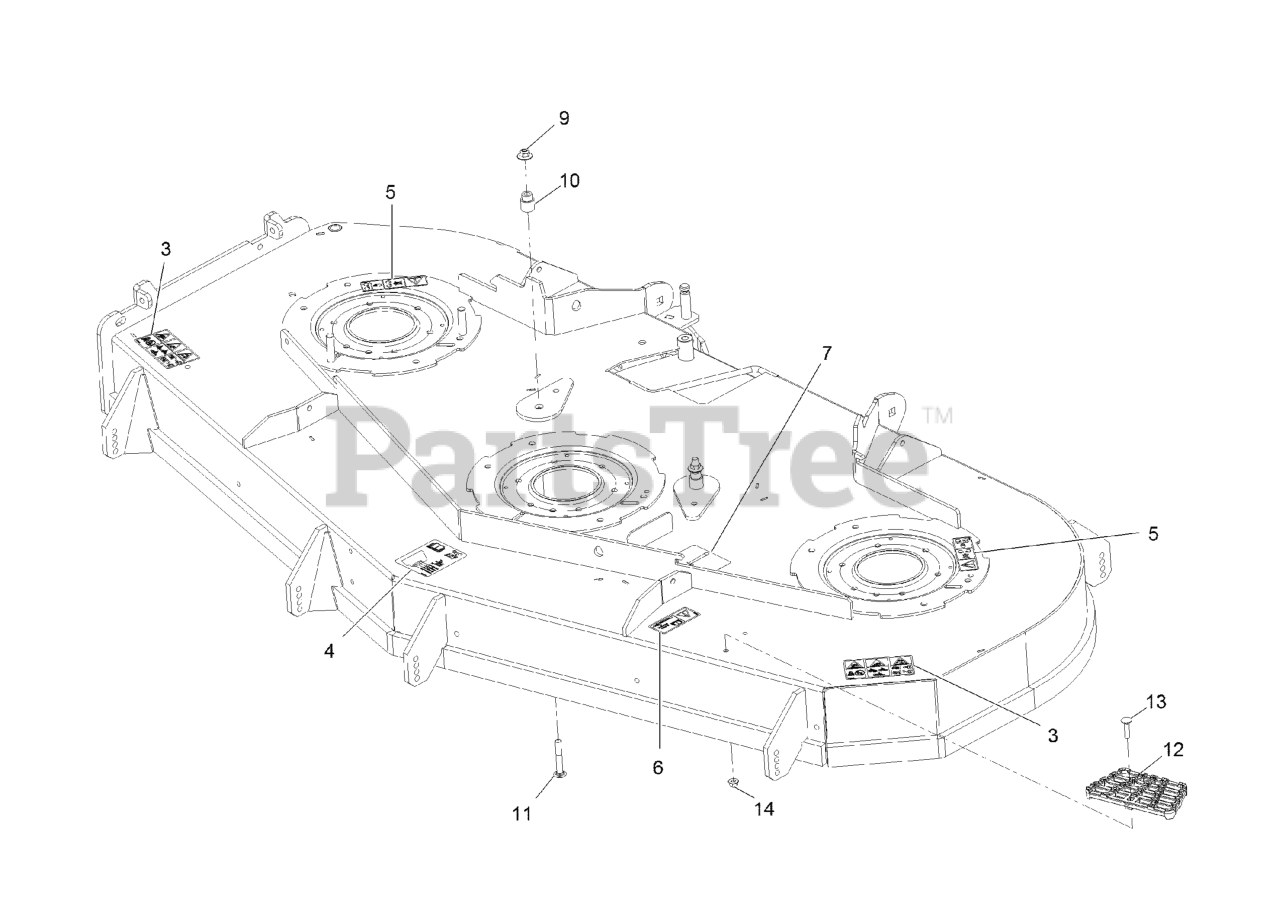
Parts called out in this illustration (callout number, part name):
3	DECAL-DANGER THROWN OBJECTS
4	DECAL-ROLLER, ANTI-SCALP
5	DECAL-COVER, MISSING
6	DECAL-TORQUE, BOLT
7	DECAL-BELT ROUTING
9	Nut-Nyloc 3/8-16 Flg
10	BUSHING-IDLER
11	SCREW-CARR
12	STEP-DECK
13	Bolt-Carriage 5/16-18 X 1 1/4
14	NUT-HF, NI
